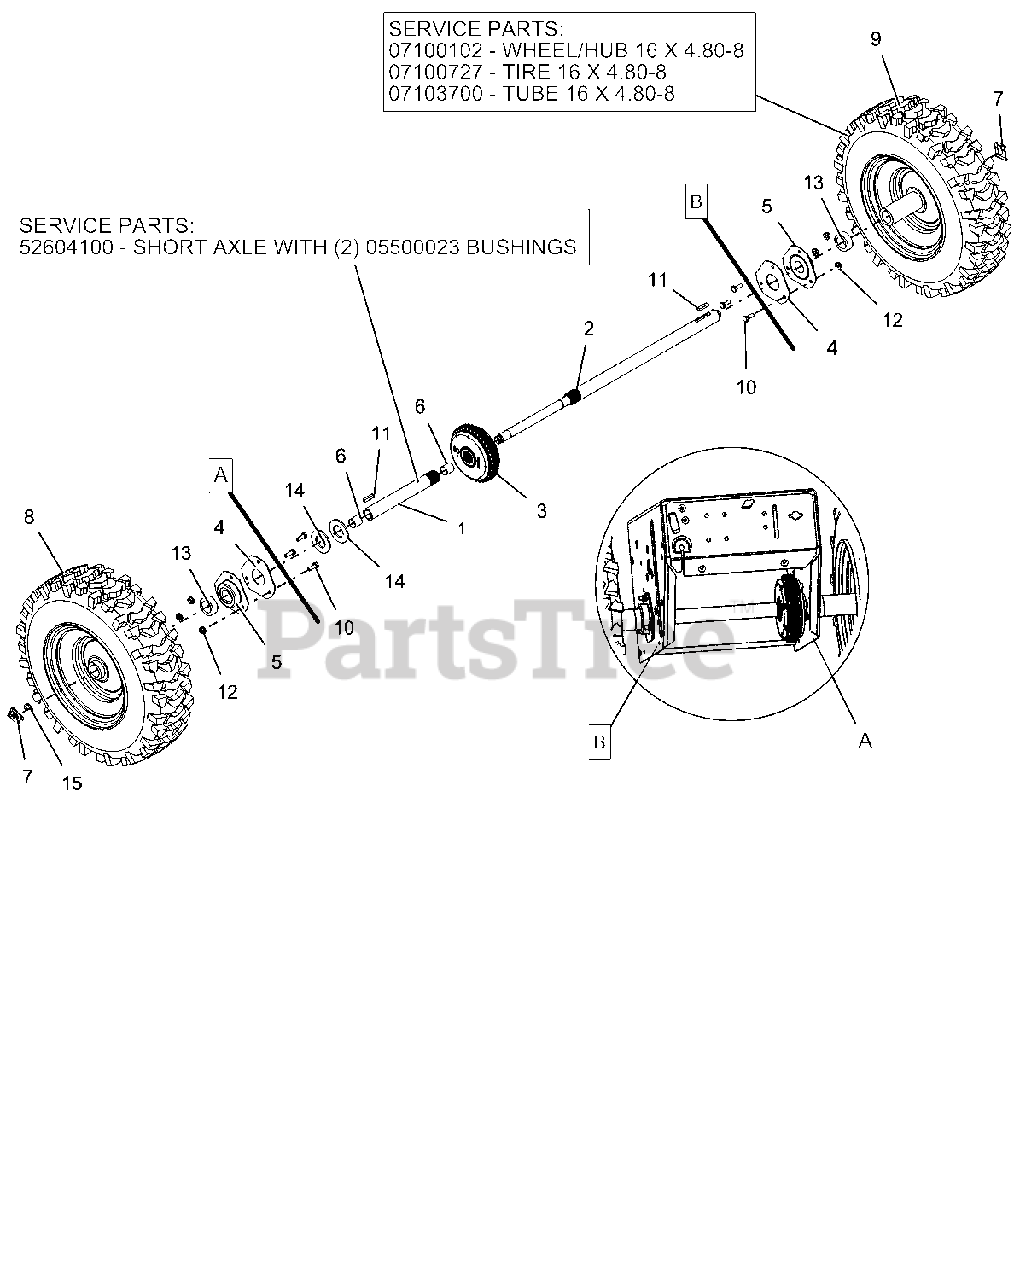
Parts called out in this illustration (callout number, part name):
1	AXLE, SHORT-PRO AUTO DIFF
2	AXLE, LONG-PRO AUTO DIFF
3	DIFFERENTIAL, AUTOMATIC
4	PLATE, BEARING SPACER
5	BRG-FLG 1.003/1.000 3 BOLT
6	BSHG-SLV .706X.764X.75 BRZ
7	CLIP, SNAP .625 DIA
8	TIRE/WHEEL,RH 16X4.8-8 DIFF T2
9	TIRE/WHEEL,LH 16X4.8-8 DIFF T2
10	@BLT-HEX .25-20X.75 GR5 YWZC
11	KEY-RECT .25X.188X1.00
12	@NUT-LK-CTR-FLG .25-20 YWZC
13	SPACER, PRO AXLE BEARING
14	WSHR-FL-STL- 1.062X2.0X.134 YZ
15	RG-RTNG-EXT .625X.042
16	HUB, WHEEL - 16X4.8-8 DIFF
17	TIRE, 4.80-8 K478
18	TUBE
19	AXLE, SHORT-AUTO W/BUSHINGS
